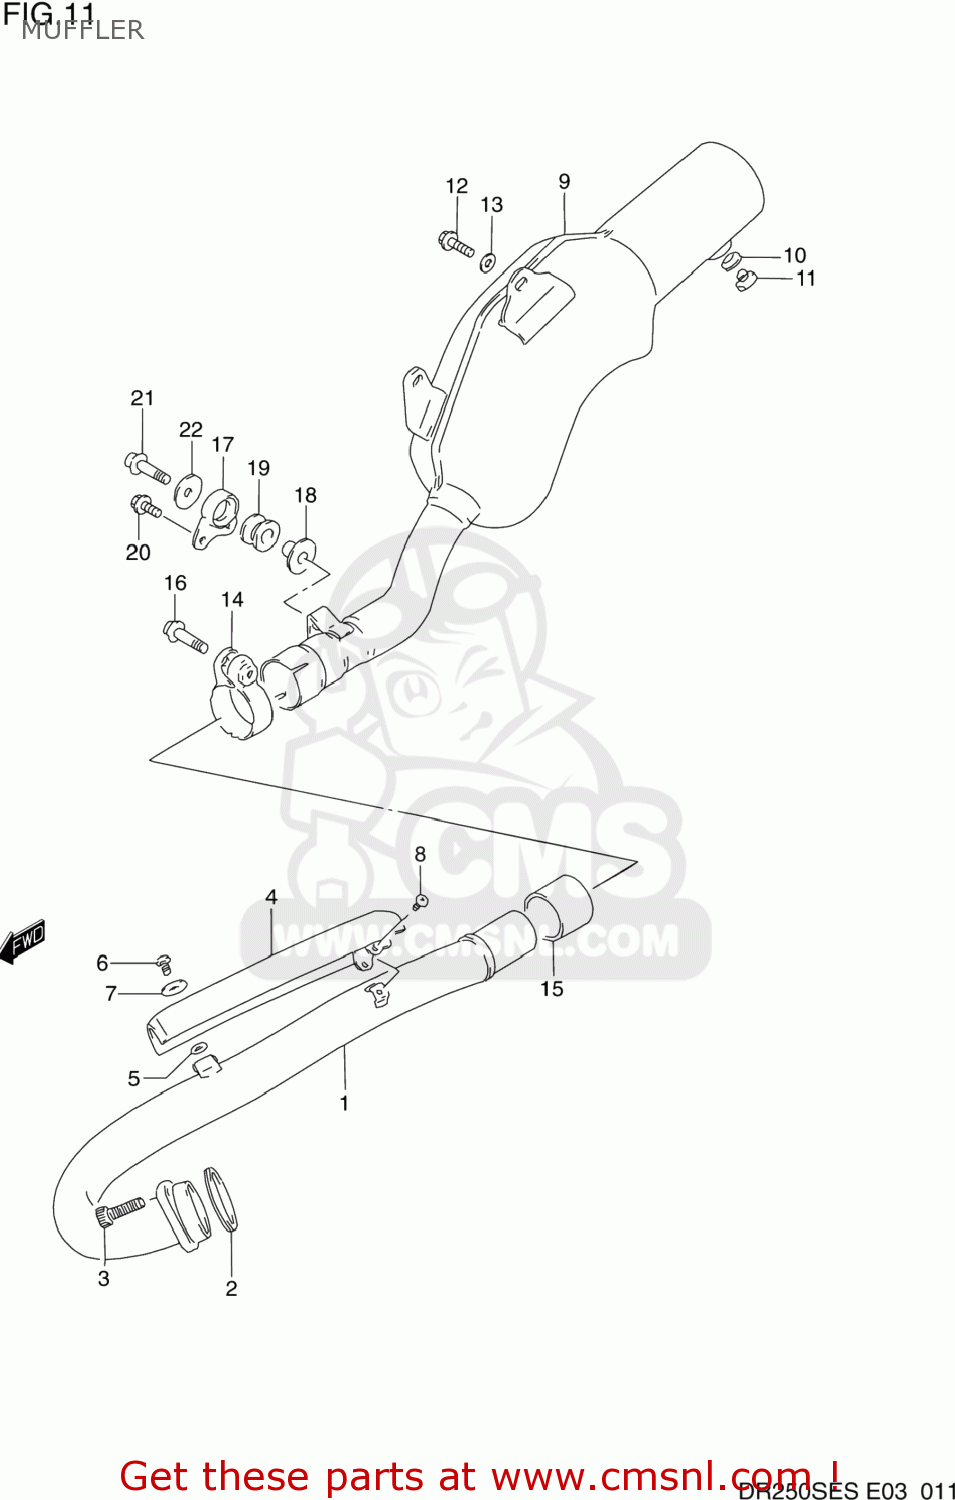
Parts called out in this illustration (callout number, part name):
1	PIPE,EXHAUST
2	GASKET (NAS)
3	BOLT
4	COVER,EXHAUST PIPE
5	GASKET(5.8X13X1.4) (NAS)
6	SCREW
7	WASHER(6.5X18X1)
8	SCREW
9	BODY,MUFFLER
10	GASKET(12.1X16.2X3.7) (NAS)
11	PLUG(12X9)
12	BOLT(8X20)
13	WASHER (8.5X19X2.3)
14	CLAMP,PREMUFFLER CONNECTOR,L
15	CONNECTOR,MUFFLER JOINT
16	BOLT
17	DAMPER,MUFFLER SUPPORT
18	SPACER(8.6X12X17.5)
19	CUSHION
20	BOLT
21	BOLT 8X35
22	WASHER (8.5X20X1.6)
